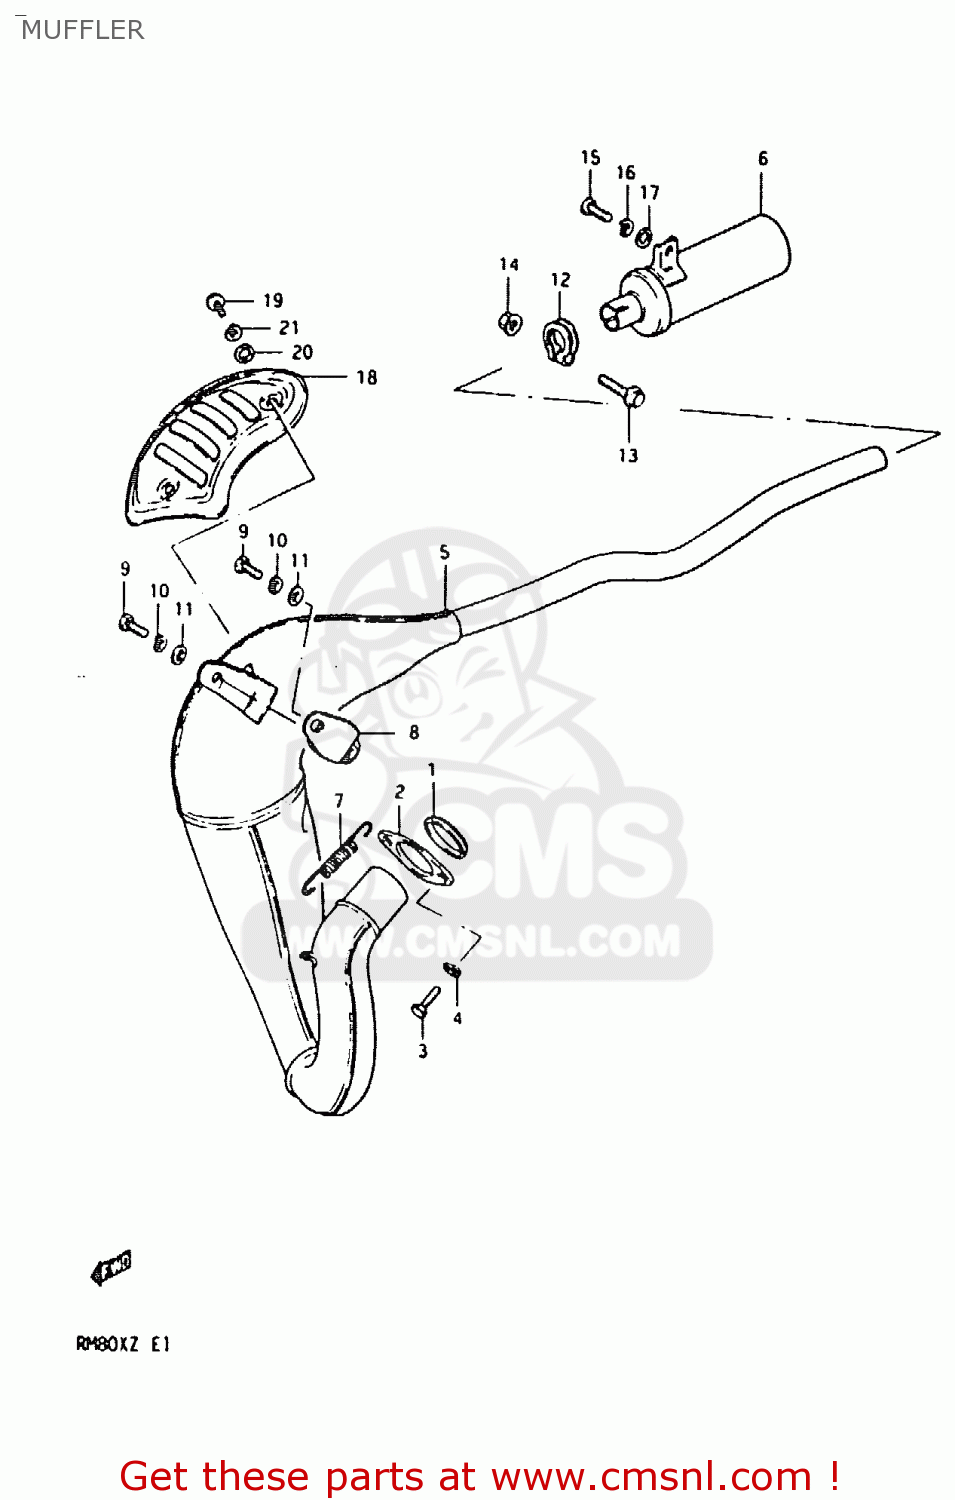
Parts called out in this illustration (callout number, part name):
1	GASKET,EXHAUST PIPE (NAS)
2	CLAMP,EXHAUST PIPE
3	BOLT, UPPER
4	LOCK WASHER
5	BODY,MUFFLER
6	BODY,MUFFLER
7	SPRING
8	DAMPER,MUFFLER SUPPORT
9	BOLT
10	LOCK WASHER
11	WASHER
12	CLAMP,EXHAUST
13	BOLT
14	NUT 6MM
15	BOLT
16	LOCK WASHER
17	WASHER
18	COVER,MUFFLER
19	SCREW
20	WASHER
21	LOCK WASHER
